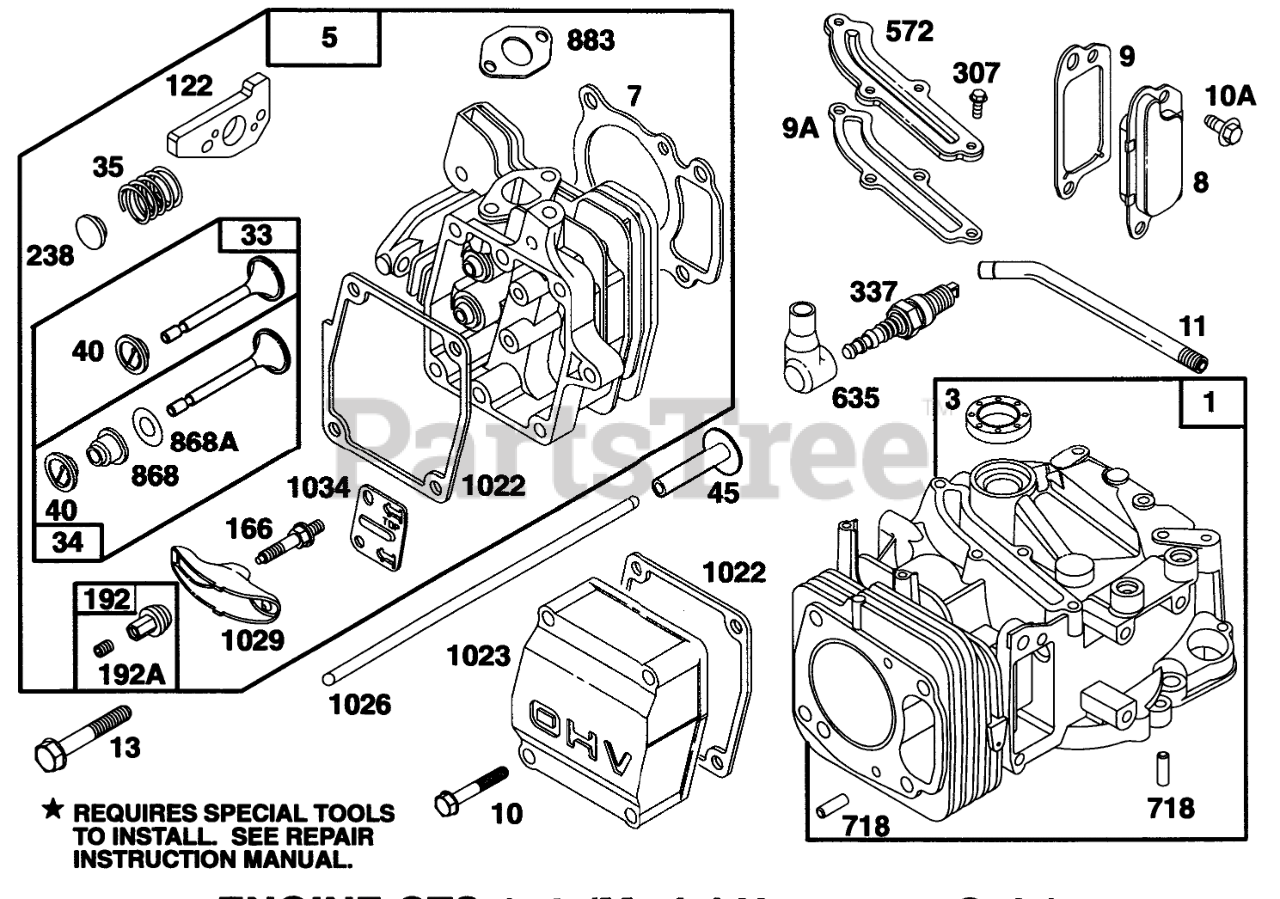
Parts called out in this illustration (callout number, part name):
1	CYLINDER ASSEMBLY
3	SEAL - OIL
5	CYLINDER HEAD
7	CYLINDER HEAD GASKET
8	Breather Assy
9	BREATHER GASKET
9A	GASKET-BREATHER
10	HEX HEAD SCREW
10A	HEX HEAD SCREW
11	TUBE - BREATHER
13	CYLINDER HEAD SCREW
33	EXHAUST VALVE
34	INTAKE VALVE
35	VALVE SPRING
37	GUARD - FLYWHEEL
40	SPRING RETAINER
45	VALVE TAPPET
122	ADAPTER ASSEMBLY
166	ROCKER ARM STUD
192	NUT - HEX SPECIAL
192A	SCREW SET
238	VALVE CAP
307	SCREW - SEM
337	PLUG-SPARK
572	BAFFLE - CYCLINDER
635	SPARK PLUG ELBOW
718	DOWEL - SLEEVE
868	SealAssy-Valve
868A	Seal-Valve
883	EXHAUST GASKET
1022	ROCKER COVER GASKET
1023	COVER - VALVE
1026	PUSH ROD
1029	ROCKER ARM
1034	PUSH ROD GUIDE
